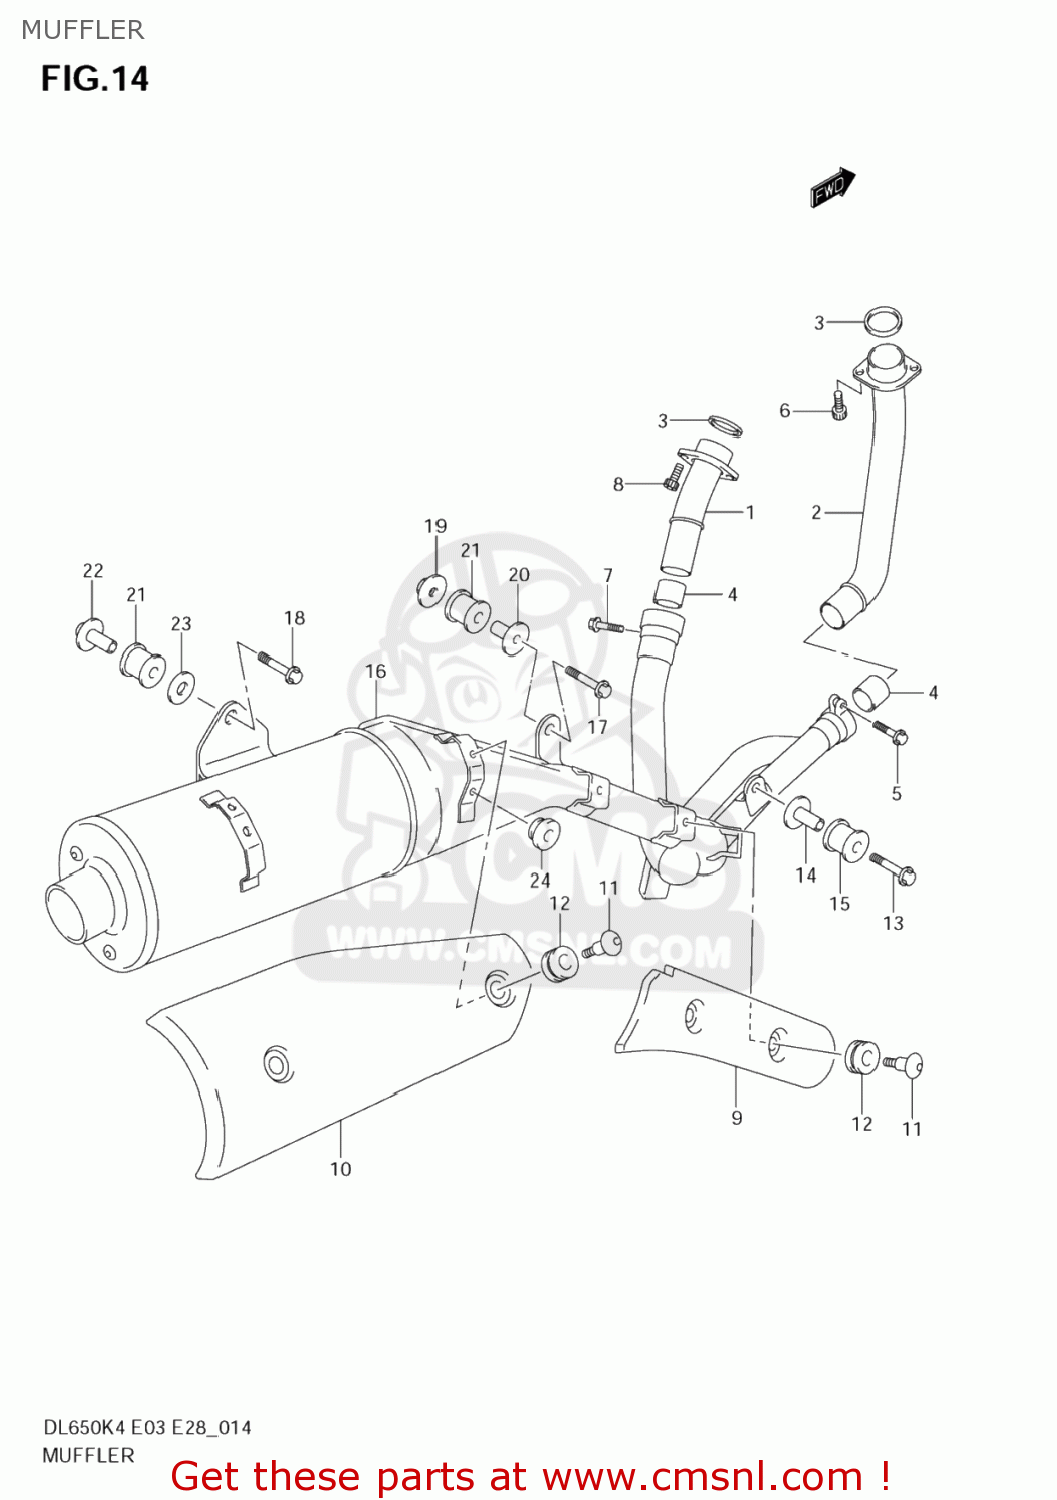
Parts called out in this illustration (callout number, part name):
1	PIPE,EXHAUST RR
2	PIPE,EXHAUST FR
3	GASKET,EXHAUST PIPE (NAS)
4	CONNECTOR,MUFFLER
5	BOLT(8X35)
6	BOLT(8X25)
7	BOLT
8	BOLT
9	COVER,MUFFLER FR
10	COVER,MUF
11	SCREW(6X20)
12	CUSHION
13	BOLT 8X45
14	SPACER(8.6X12X24.2)
15	CUSHION
16	MUFFLER
17	BOLT
18	BOLT(8X45)
19	NUT,MUFFLER SUPPORT FR
20	SPACER(8.6X12X27.1)
21	CUSHION
22	NUT,MUFFLER SUPPORT
23	WASHER(8.5X33X1.5)
24	CUSHION
